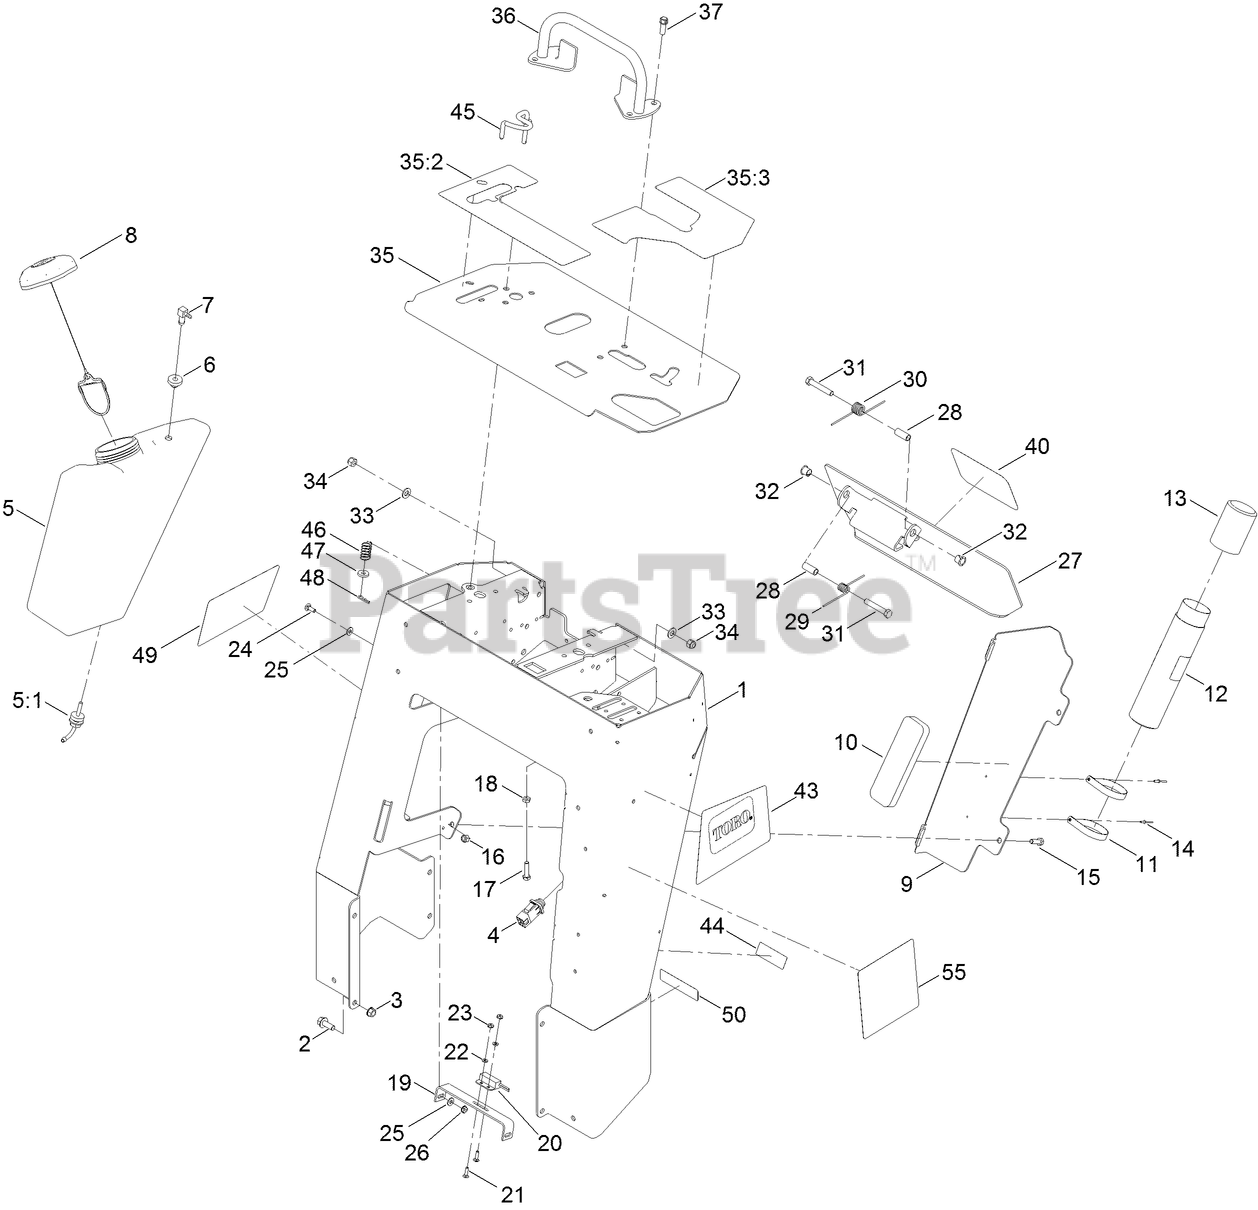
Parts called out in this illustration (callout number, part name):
2	SCREW-HHF
3	NUT-FLANGE
4	SWITCH-PLUNGER
5	TANK-FUEL
5:1	FITTING-FUEL, BULKHEAD
6	BUSHING
7	FITTING-ELBOW, 90 DEG
8	CAP-FUEL, RATCHETING
9	BRACKET-COVER, TANK
10	PAD-FOAM
11	CLAMP-R
12	TUBE-MANUAL
13	CAP-HOUSING
14	RIVET-POP
15	SCREW-HH
16	NUT-LOCK, NI
17	SCREW-HH
18	NUT-JAM
19	PLATE-SWITCH
20	SWITCH-PROXIMITY
21	SCREW-CARR
22	WASHER-FLAT
23	NUT-KEPS
24	BOLT-CARR
25	WASHER-FLAT
26	NUT-KEPS
27	PLATE-REVERSE
28	SPACER-SPRING
29	SPRING-TORSION, LH
30	SPRING-TORSION, RH
31	SCREW-HH
32	BUSHING-NYLINER
33	WASHER-FLAT
34	NUT-LOCK, NI
35	PANEL-CONTROL
35:2	DECAL-CONSOLE, RH
35:3	DECAL-CONSOLE, LH
36	BAR-REFERENCE
37	SCREW-TAPTITE
43	DECAL-SIDE, LH
44	DECAL-INFO
45	ROD-INTERLOCK
46	SPRING-CONTROL
47	WASHER-FLAT
49	DECAL-SIDE, RH
50	DECAL-ARRESTOR, SPARK
55	DECAL-SERVICE
